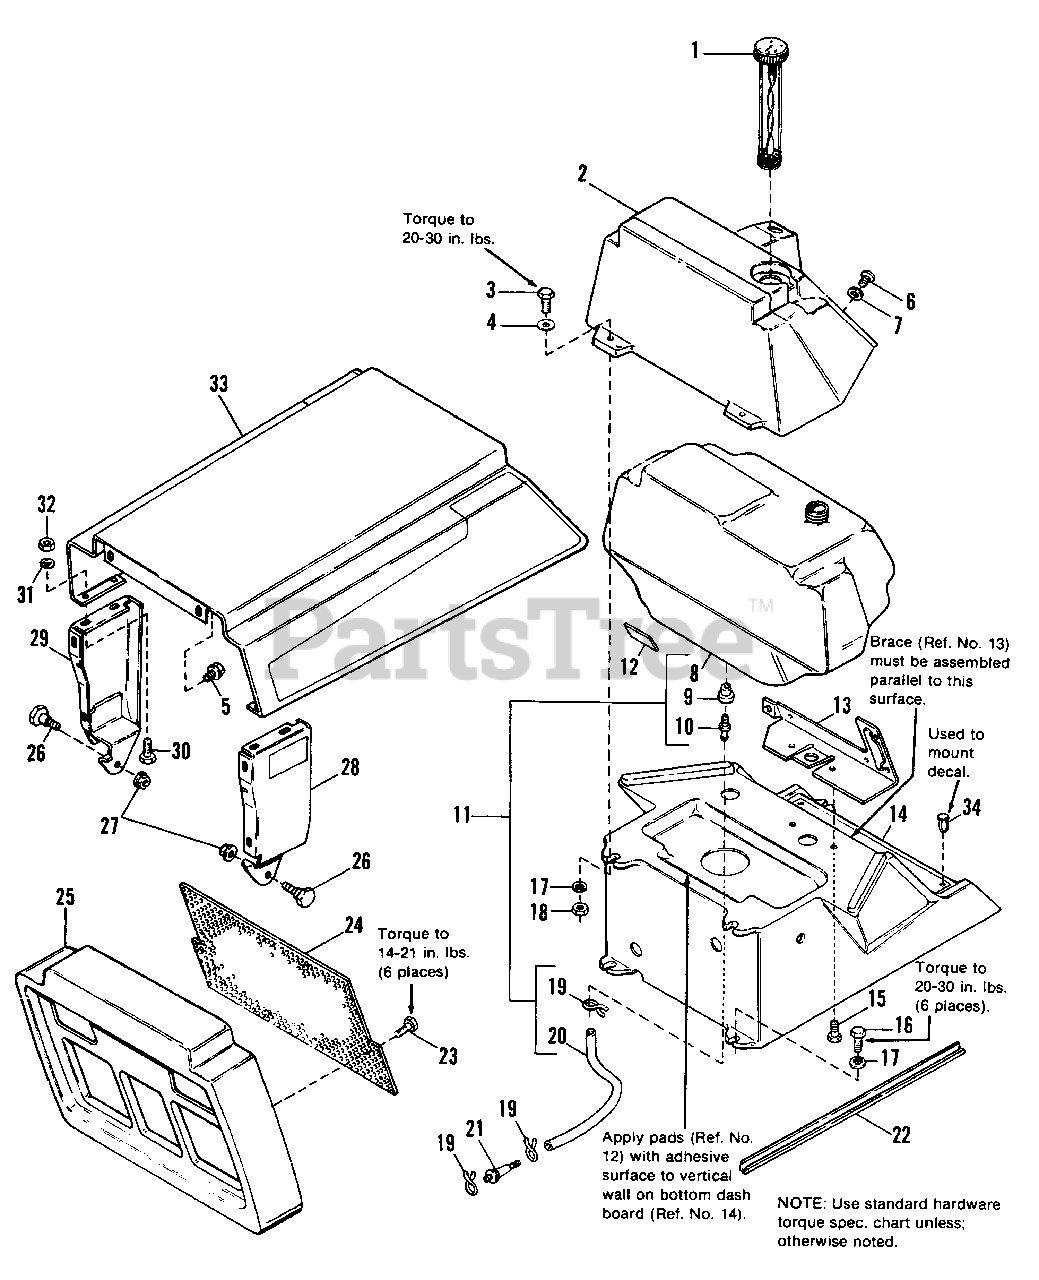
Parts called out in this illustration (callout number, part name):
1	CAP, Fuel Tank
2	DASHBOARD, Top
3	CAPSCREW, Hex, 1/4-20 x 1-1/4
4	WASHER, 1/4
5	SCREW. Plastite, 1/4 x 1
6	SCREW, Taptite Phillips, 1/4-20 x 3/4
7	WASHER, 3/16
11	TANK ASSY., Fuel
14	DASHBOARD, Bottom
15	SCREW, Taptite, 1/4-20 x 3/4
16	SCREW, Taptite, 1/4-20 x 1
17	LOCKWASHER, Dish, 1/4
18	LOCKNUT, Hex, 1/4-20
19	CLAMP, Hose
21	FILTER, Fuel
22	EDGING, Lower Dash
23	SCREW, Plastite, #10-14 x 1/2
25	GRILLE (1690759 & 1690846 only)
25	GRILLE 1690912 only)
26	BOLT, Shoulder, 5/16-18 x 7/8
27	LOCKNUT, Flange, Whiz, 5/16-18
28	PANEL ASSY., L.H.
29	PANEL ASSY., R.H.
30	CAPSCREW, Hex, 1/4-20 x 1/2
31	LOCKWASHER, 1/4
32	NUT, Hex, 1/4-20
34	CLIP, Canoe
